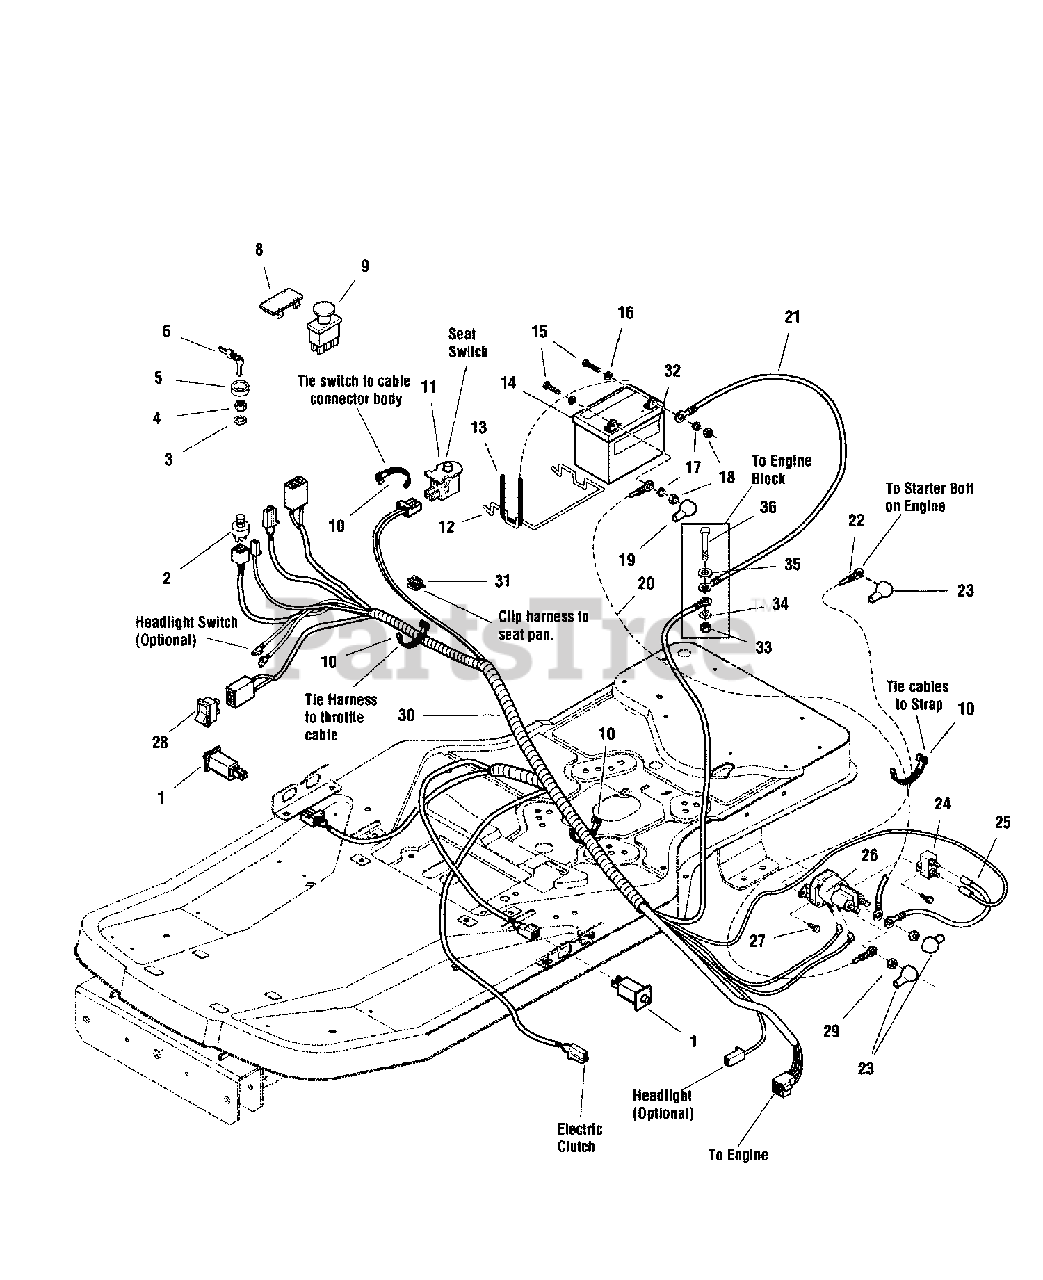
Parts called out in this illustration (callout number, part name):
1	SWITCH, Push Button (NO/NC) Snap-In
2	SWITCH ASSEMBLY, Ignition
3	LOCKWASHER, Internal Tooth 5/8" Thin
4	NUT, 5/8-32 Hex Flange (Ignition Switch Die Cast)
5	COVER, Ignition Switch
6	KEYS, Blister Pk (KIDS+MWRS DON'T MIX) (set of two, one coated)
8	PLUG, Hole (Black Plastic)
9	SWITCH, PTO, Push/Pull Symbols
10	TIE, Self Locking, .184 Wide 7.31 Long
11	SWITCH, Push Button (NC)
12	BRACE, Battery, .19 Dia. Wire
13	STRAP, Black Rubber, .19 Square 7.88 O.D. Battery
14	BATTERY, 12 Volt, 230 CCA
15	SCREW, 1/4-20 x 3/4" Hex Head Cap, GR5
16	WASHER, 1/4, .27 I.D. x .62 O.D. x .05 Thick
17	WASHER, 1/4" Spring Lock
18	NUT, 1/4-20 Hex
19	BOOT, Insulator, Red PVC Warning
20	CABLE, #6 x 10 Long, Red Two-Ring Terminals
21	CABLE, # 6 x 26 Long, Two-Ring Terminals
22	CABLE, #6 x 15 Long, Two-Ring Terminals
23	COVER, Terminal - Red PVC
24	BREAKER, Circuit 12 Volt 20 AMP
25	WIRE, 12 Gage
26	SOLENOID, Super Trombetta - 2 Terminal
27	SCREW, 1/4-20 x 1/2" Hex Washer Head Screw - Black (Taptite)
28	SWITCH, Electric Height-of-Cut
29	NUT, 5/16-24 Hex Keps
30	HARNESS, Wiring
31	CLIP, Cable, .390 Wire Dia.
32	DECAL, Danger Poison
33	NUT, 5/16-18 Hex Flange Lock, Black
34	WASHER, 3/8" External Tooth Lock
35	WASHER, .312 (.34 I.D. x.75 O.D.)
36	SCREW, 5/16-18 x 2" Hex Head Cap
